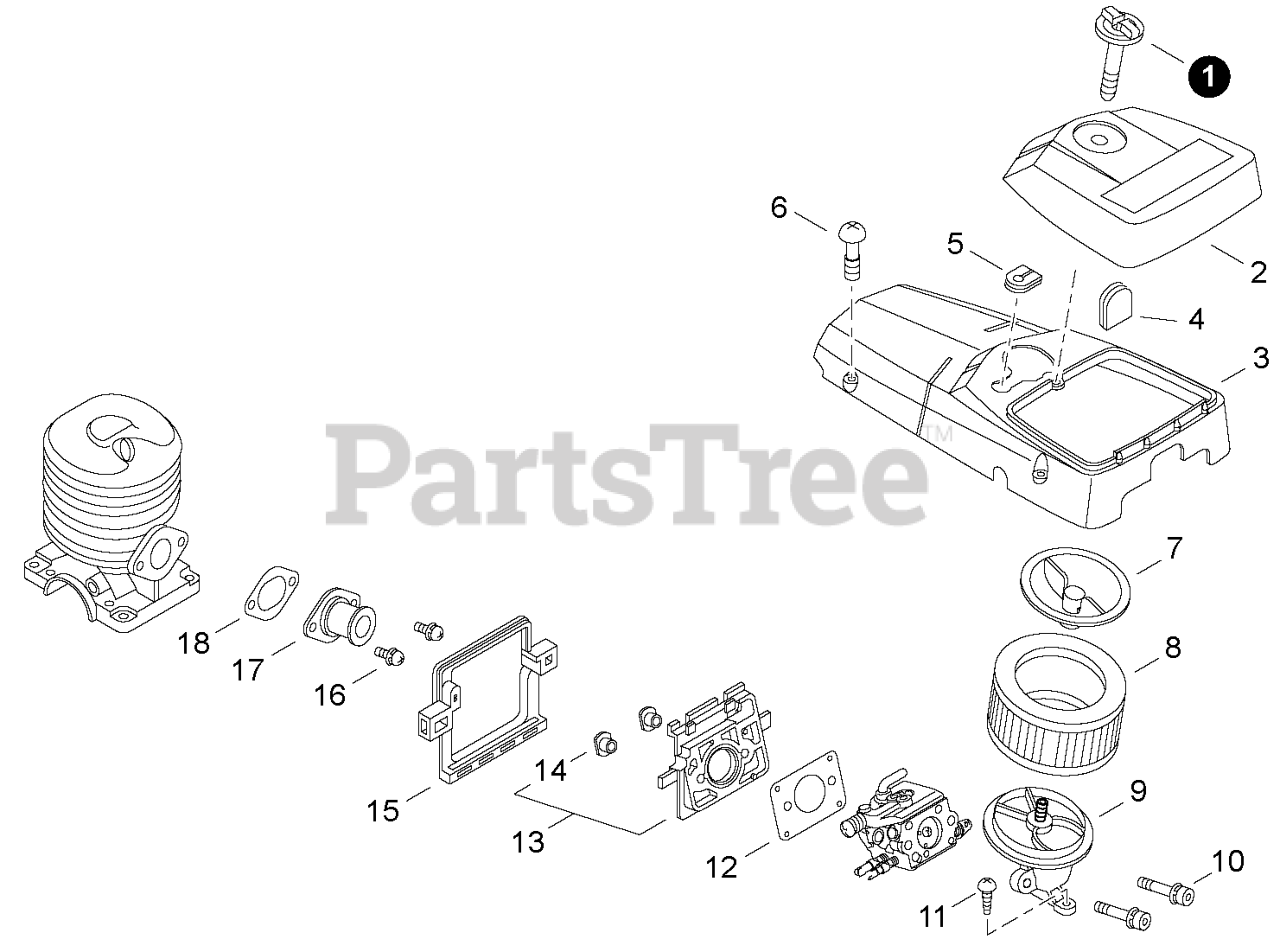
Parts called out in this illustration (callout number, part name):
1	THUMBSCREW
2	COVER, AIR FILTER
3	COVER, ENGINE
5	GROMMET
7	CAP, AIR FILTER
8	FILTER, AIR - HEAVY DUTY
9	ADAPTOR, INTAKE
10	BOLT 5x50
11	SCREW 5x16
12	GASKET, INTAKE
13	INSULATOR KIT, INTAKE
15	CUSHION
16	SCREW 5x12
17	ADAPTOR, INTAKE
18	GASKET, INTAKE
